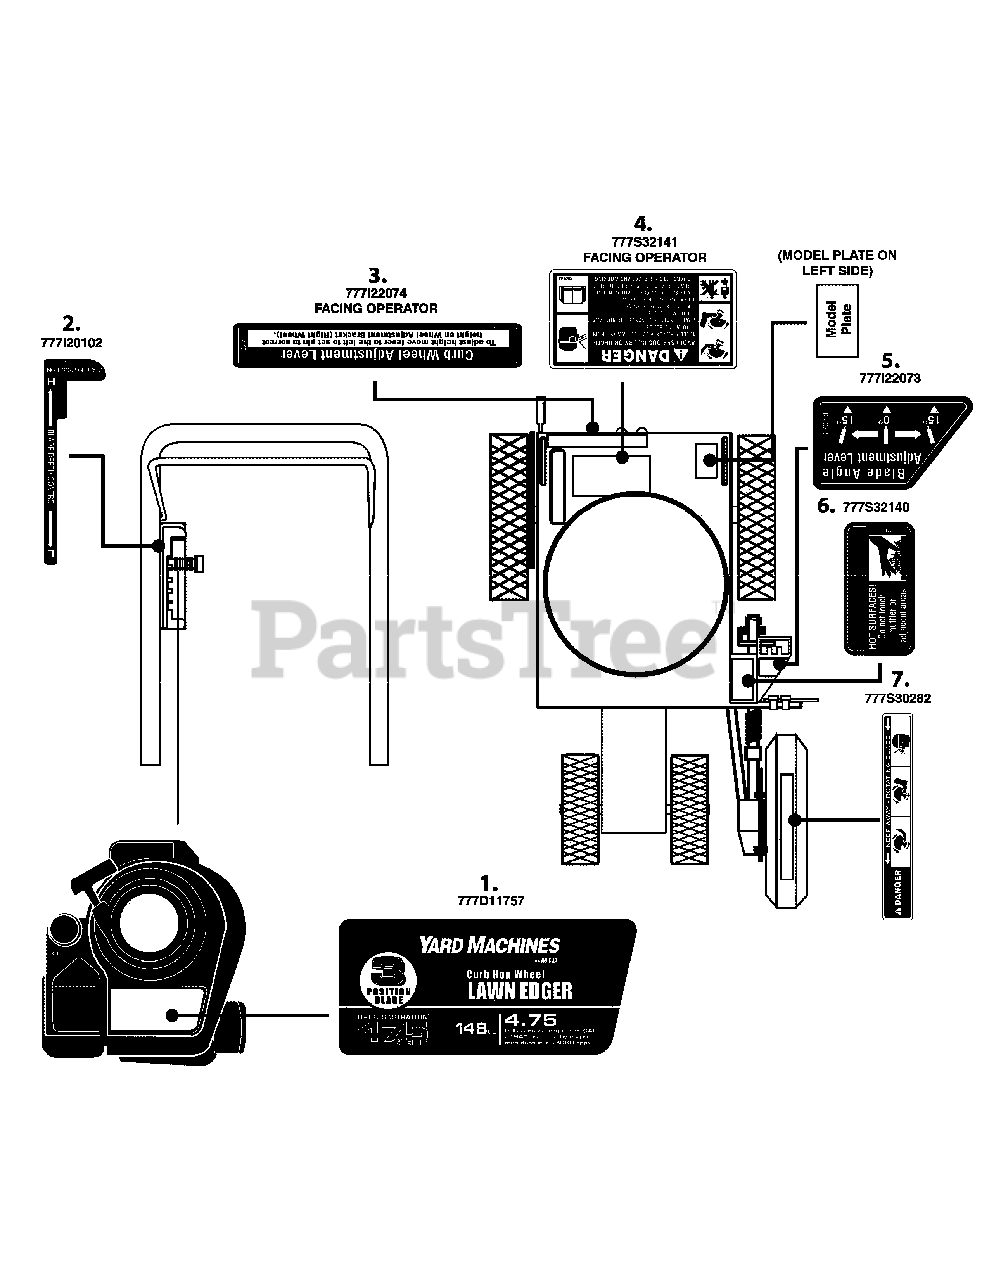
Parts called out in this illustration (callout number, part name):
1	LABEL-EDGER SHROUD YARD MACHINE
2	LABEL DEPTH CNTRL
3	LABEL-FRAME REAR
4	LABEL-FRAME REAR
5	LABEL-FRAME LH
6	LABEL-MUFFLER
7	LABEL-BLADE COVER
